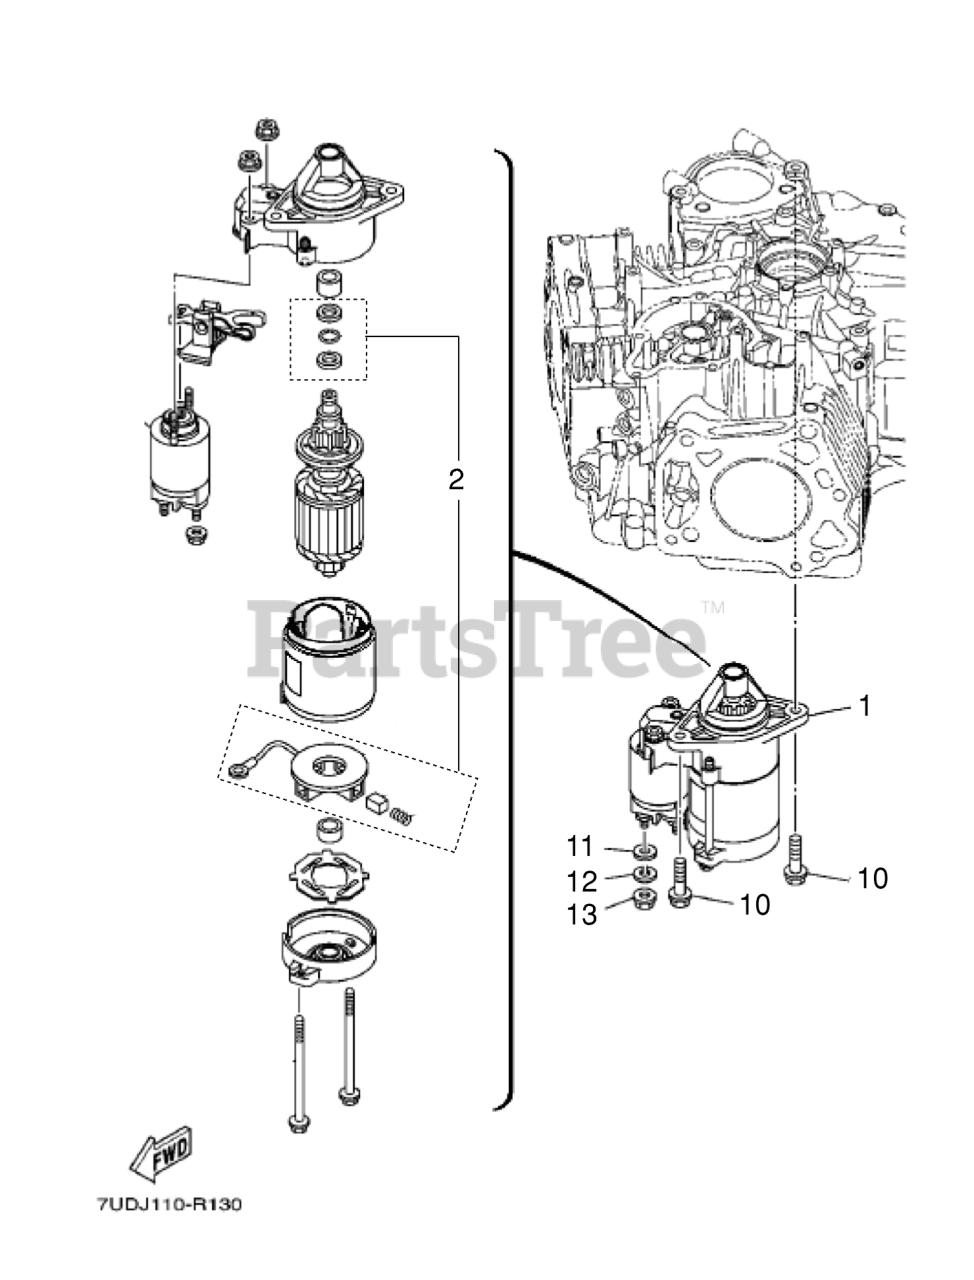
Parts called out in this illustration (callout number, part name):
1	STARTER ASSY YAMAHA PN: 7UD-H
2	BUSH BRUSH HOLDER ASSY
10	BOLT YAMAHA PN: 95822-08030
11	WASHER YAMAHA PN: 90201-08879
12	WASHER YAMAHA PN: 92902-08100
13	NUT YAMAHA PN: 95302-08600
